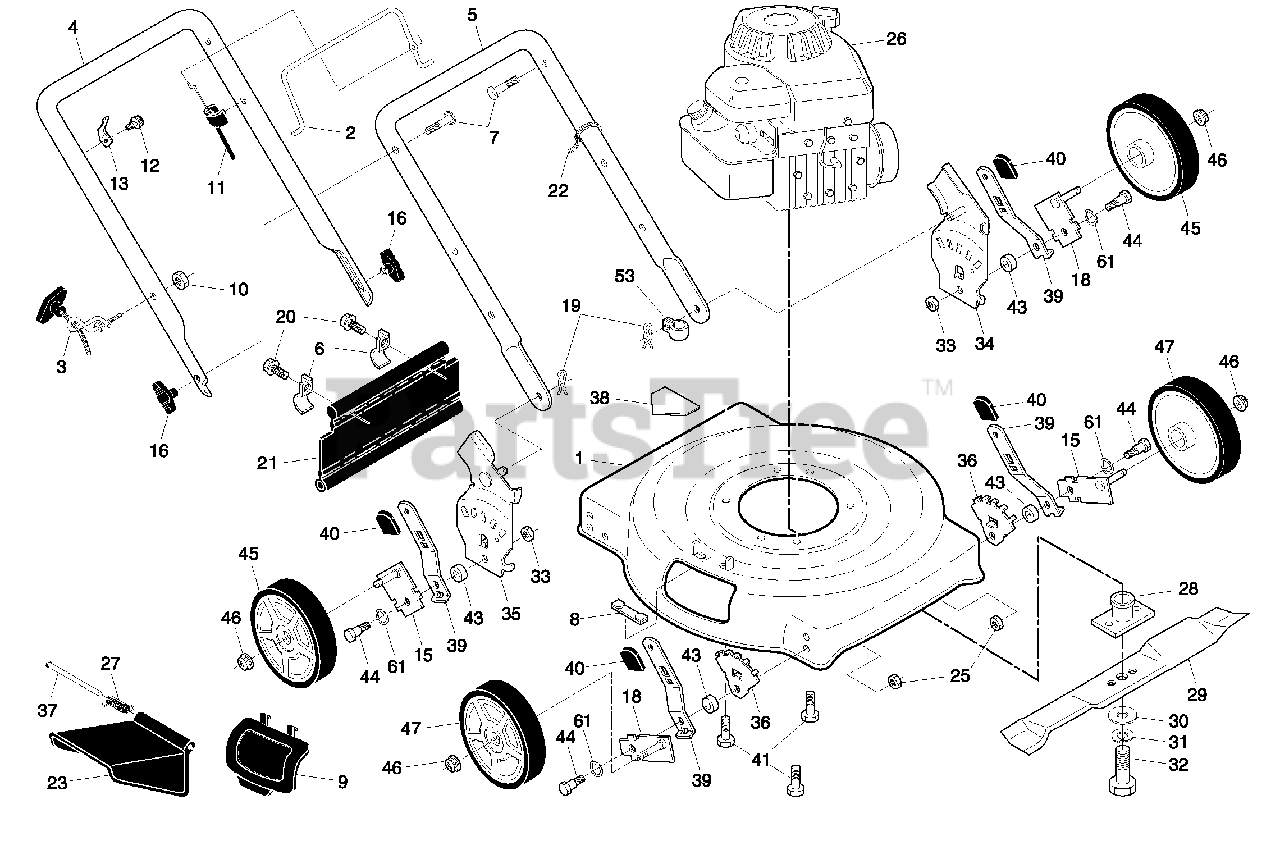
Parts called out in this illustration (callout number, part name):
1	Lawn Mower Housing Assembly
2	Control Bar
3	Rope Guide
4	Upper Handle
5	Lower Handle
6	Hinge Bracket
7	Handle Bolt 5/16-18
8	Clip, Closeout
9	Mulcher Plate
10	Locknut, Hex 1/4-20
11	Engine Zone Control Cable
12	Screw, Hex Head, Threaded, Rolled #10-24 x1/2
13	Up-Stop Bracket
15	Axle Arm Assembly (Rear, RH / Front, LH)
16	Handle Knob
18	Axle Arm Assembly (Rear, LH / Front, RH)
19	Hairpin Cotter
20	Screw
21	Rear Skirt
22	Wire Tie
23	Discharge Guard
25	Nut, Hex
27	Torsion Spring
28	Blade Adapter
29	22" Blade
30	Hardened Washer
31	Helical Lockwasher 3/8
32	Hex Head Screw 3/8-24 x 1/4 Grade 8
33	Nut, Hex, Centerlock 5/16-18
34	Support, Wheel Bracket, LH
35	Support, Wheel Bracket, RH
36	Adjuster, Wheel Bracket
37	Hinge Rod
38	Danger Decal
39	Selector Spring
40	Selector Knob
41	Screw, Hex Head, Threaded, Rolled 3/8-16 x 1
43	Washer
44	Shoulder Bolt
45	Wheel & Tire Assembly, Rear, 8 x 1-3/4
46	Locknut, Hex 3/8-16
47	Wheel & Tire Assembly, Front, 7 x 1-3/4
53	Clip, Cable
61	Washer, Curved
